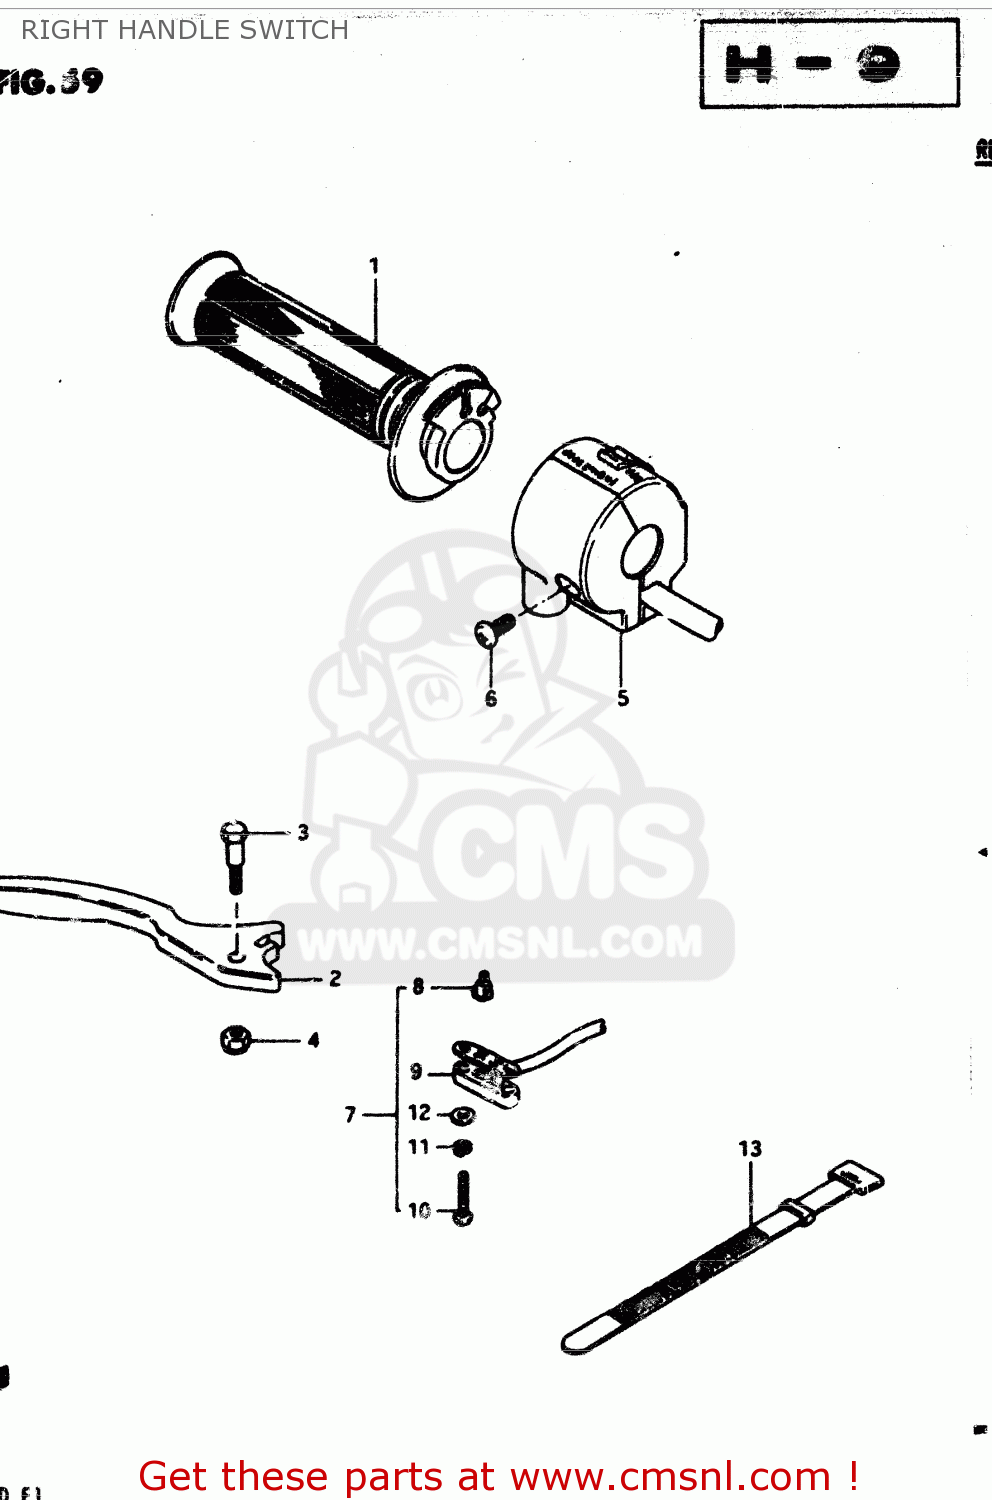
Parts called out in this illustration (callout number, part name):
1	GRIP,THROTTLE
2	LEVER,BRAKE
3	BOLT
4	NUT 6MM
5	SWITCH ASSEMBLY,HANDLE,RIGHT
6	SCREW
7	SWITCH ASSEMBLY
8	CONTACT,SWITCH
9	COVER,FR BK TERMINAL BASE
10	SCREW
11	LOCK WASHER
12	WASHER
13	CLAMP(L:120)
